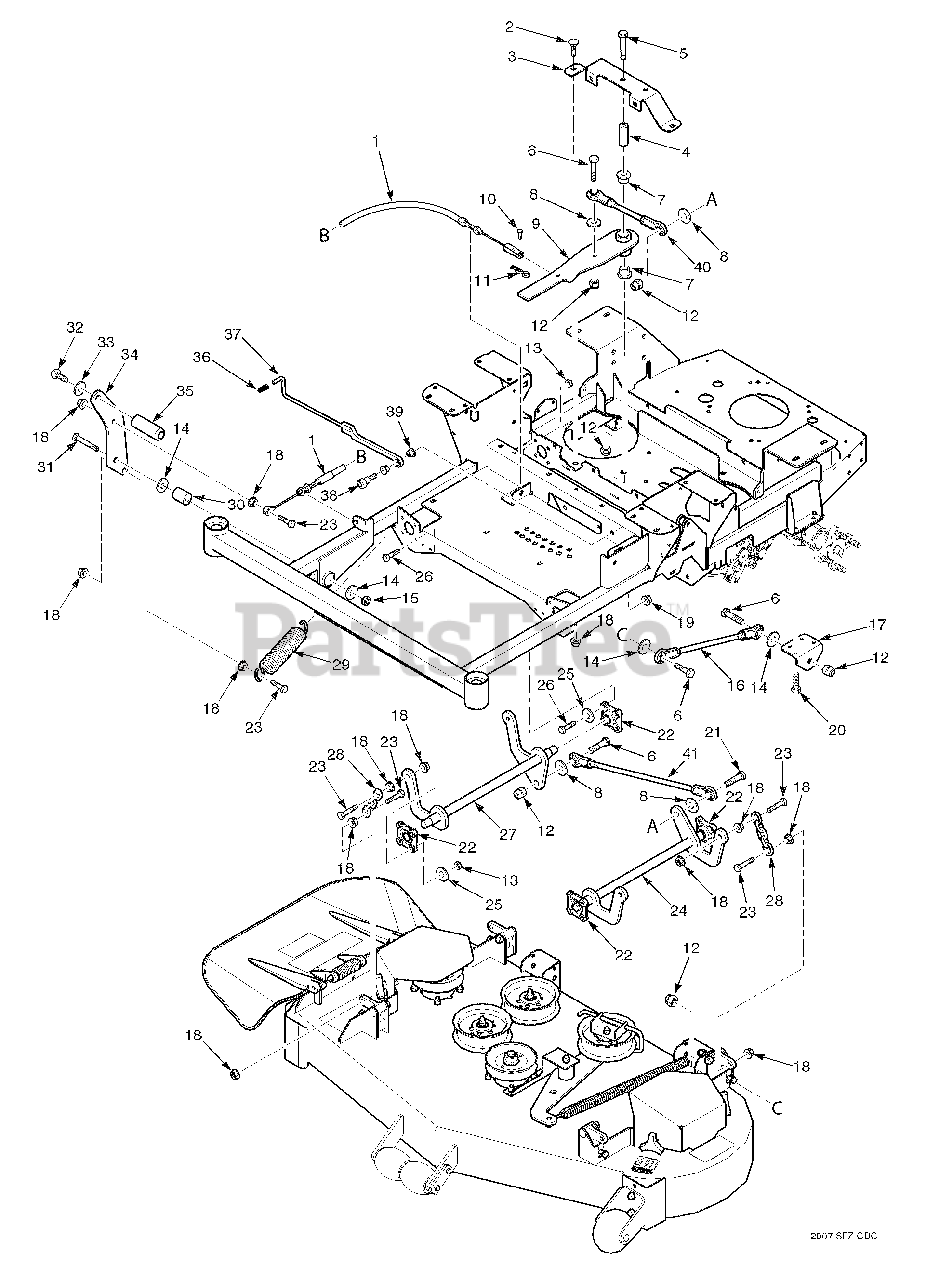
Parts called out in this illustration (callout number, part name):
1	Cable, Deck Lift
2	Bolt, Carriage 3/8-16 x 3/4"
3	Support, Idler Arm
4	Spacer, Deck Lift Pivot
5	Bolt, Hex Head 1/2-13 x 3-1/4"
6	Bolt, Hex Head 1/2-13 x 1-3/4"
7	Bearing
8	Flatwasher, 1/2-.531 x 1.06 x .095
9	Deck Lift Bellcrank Assy.
10	Clevis Pin, 5/16 x 3/4"
11	Hair Pin, .094 x 1.62"
12	Nut, Elastic Stop 1/2-13
13	Nut, Elastic Stop 5/16-18
14	Flatwasher, 1/2-.562 x 1.375 x .109
15	Nut, Center Lock 1/2-13
16	Linkage, Push Arm
17	Bracket, Push Arm Link
18	Nut, Serrated Flange 3/8-16
19	Nut, Elastic Stop 3/8-16
20	Bolt, Hex Head 5/16-18 x 3"
21	Bolt, Hex Head 1/2-13 x 2-1/2"
22	Bearing, Deck Lift
23	Bolt, Hex Head 3/8-16 x 1-1/2"
24	Weldment, Deck Lift LH
25	Flatwasher, 1/4-.312 x .750 x .065
26	Bolt, Hex Head 5/16-18 x 1"
27	Weldment, Deck Lift RH
28	Chain, Deck Lift
29	Spring, Deck Lift
30	Sleeve, Deck Lift Pivot
31	Bolt, Hex Head 1/2-13 x 3"
32	Bolt, Hex Socket 5/8-11 x 1-1/2"
33	Lockwasher, 5/8" Spring
34	Pedal, Foot Bracket
35	Foot Pedal
36	Grip, Deck Latch
37	Weldment, Deck Latch
38	Bolt, Shoulder 1/2 x 1/2"
39	Bearing
40	Linkage Assy., Deck Lift
41	Linkage Assy., Deck Lift
